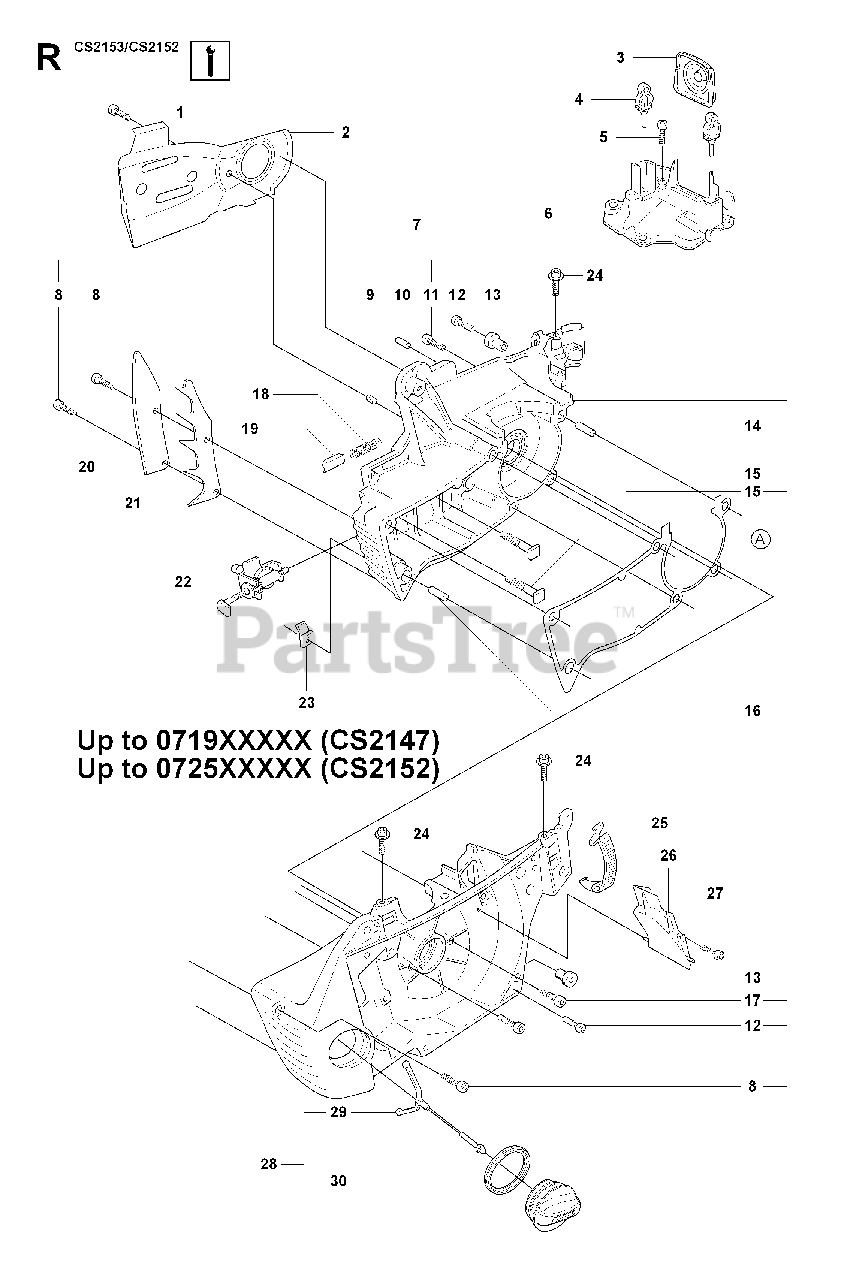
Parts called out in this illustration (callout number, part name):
7	CRANKCASE ASSY.
13	MOVEMENT LIMITER
18	LOCK SPRING
21	FELLING DOG
22	CHAIN TENSIONER
23	CHAIN CATCHER
26	DEFLECTOR
30	OILCAP GASKET
A	GASKET SET
